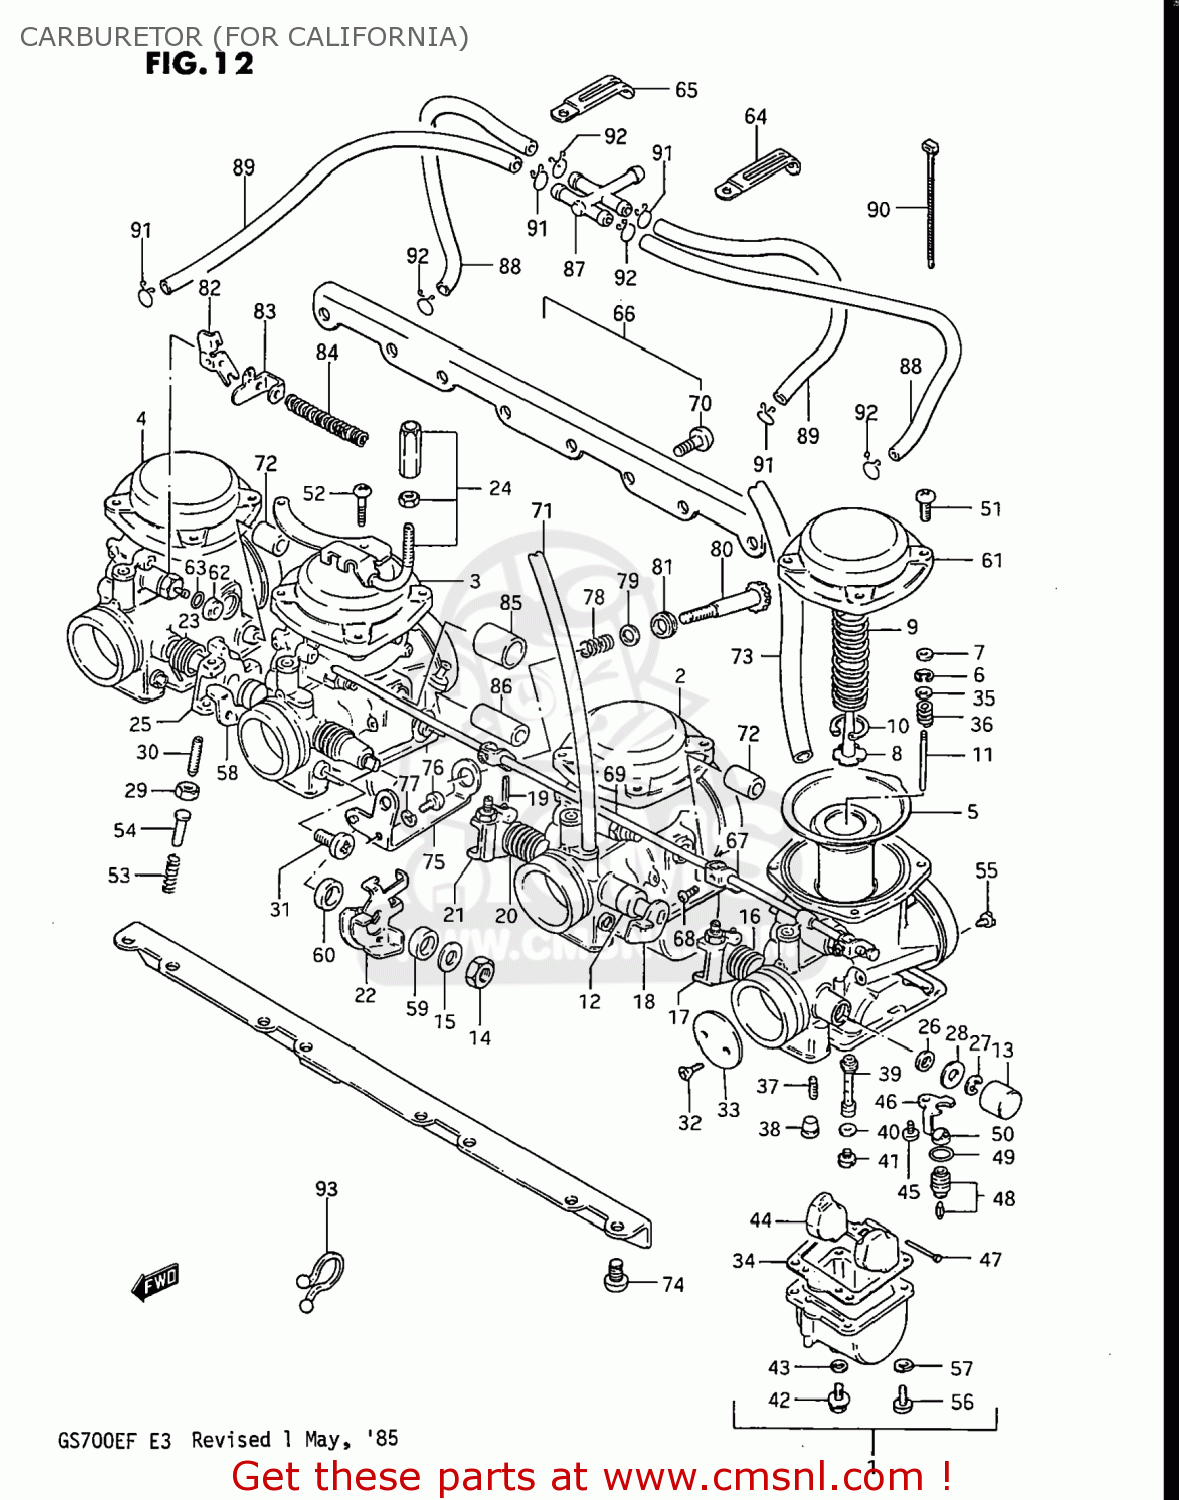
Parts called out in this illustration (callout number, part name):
1	CARBURETOR ASSEMBLY
2	CARBURETOR ASSEMBLY,MIDDLE
3	CARBURETOR ASSEMBLY
4	CARBURETOR ASSEMBLY
5	DIAPHRAGM ASSEMBLY
6	CLIP,NEEDLE
7	RING
8	HOLDER,GUIDE
9	SPRING,DIAPHRAGM
10	E RING
11	NEEDLE JET
12	GASKET
13	CAP
14	NUT 8MM
15	WASHER
16	SPRING,THROTTLE SHAFT
17	SHAFT,THROTTLE
18	SHAFT,THROTTLE
19	PIN,THROTTLE SHAFT
20	SPRING,THROTTLE SHAFT
21	LEVER,THROTTLE SHAFT
22	LEVER ASSEMBLY,THROTTLE
23	SPRING,THROTTLE SHAFT
24	BRACKET,THROTTLE CABLE
25	SHAFT,THROTTLE
26	SEAL
27	E RING
28	GASKET,THROTTLE SHAFT (NAS)
29	NUT
30	SCREW
31	SCREW
32	SCREW
33	VALVE,THROTTLE (BUTTERFLY)
34	GASKET,FLOAT CHAMBER (NAS)
35	WASHER
36	SPRING
37	JET,PILOT(37.5)
38	PLUG,NEEDLE JET
39	JET,NEEDLE
40	WASHER,NEEDLE NOZZLE
41	JET,MAIN(122.5)
42	PLUG,DRAIN
43	GASKET (NAS)
44	FLOAT
45	SCREW 4X6
46	PLATE,NEEDLE VALVE FITING
47	PIN,FLOAT
48	VALVE ASSEMBLY,NEEDLE
49	O-RING,NEEDLE VALVE
50	FILTER
51	SCREW
52	SCREW
53	SPRING,THROTTLE SCREW
54	PIN,THROTTLE LEVER
55	JET
56	SCREW
57	LOCK WASHER
58	SHAFT,THROTTLE
59	RING
60	RING
61	COVER
62	CAP,STARTER VALVE
63	O RING
64	CLIP
65	CLAMP L:35
66	CARBURETOR ASSEMBLY
67	LEVER
68	SCREW,THROTTLE ADJUST
69	SHAFT,STARTER
70	SCREW
71	HOSE 4.5X8X390
72	NIPPLE,CARBURETOR
73	HOSE
74	SCREW 6X12
75	BRACKET,THROTTLE ADJUST
76	SCREW
77	LOCK WASHER
78	SPRING
79	WASHER
80	ADJUSTER
81	BUSH
82	LEVER,CHOKE CABLE
83	PLATE,CHOKE CABLE
84	SPRING,CHOKE CABLE
85	HOSE
86	NIPPLE,CARBURETOR
87	SPRING
88	HOSE
89	HOSE
90	CLAMP
91	CLIP
92	CLIP
93	CLIP(ID:16)
